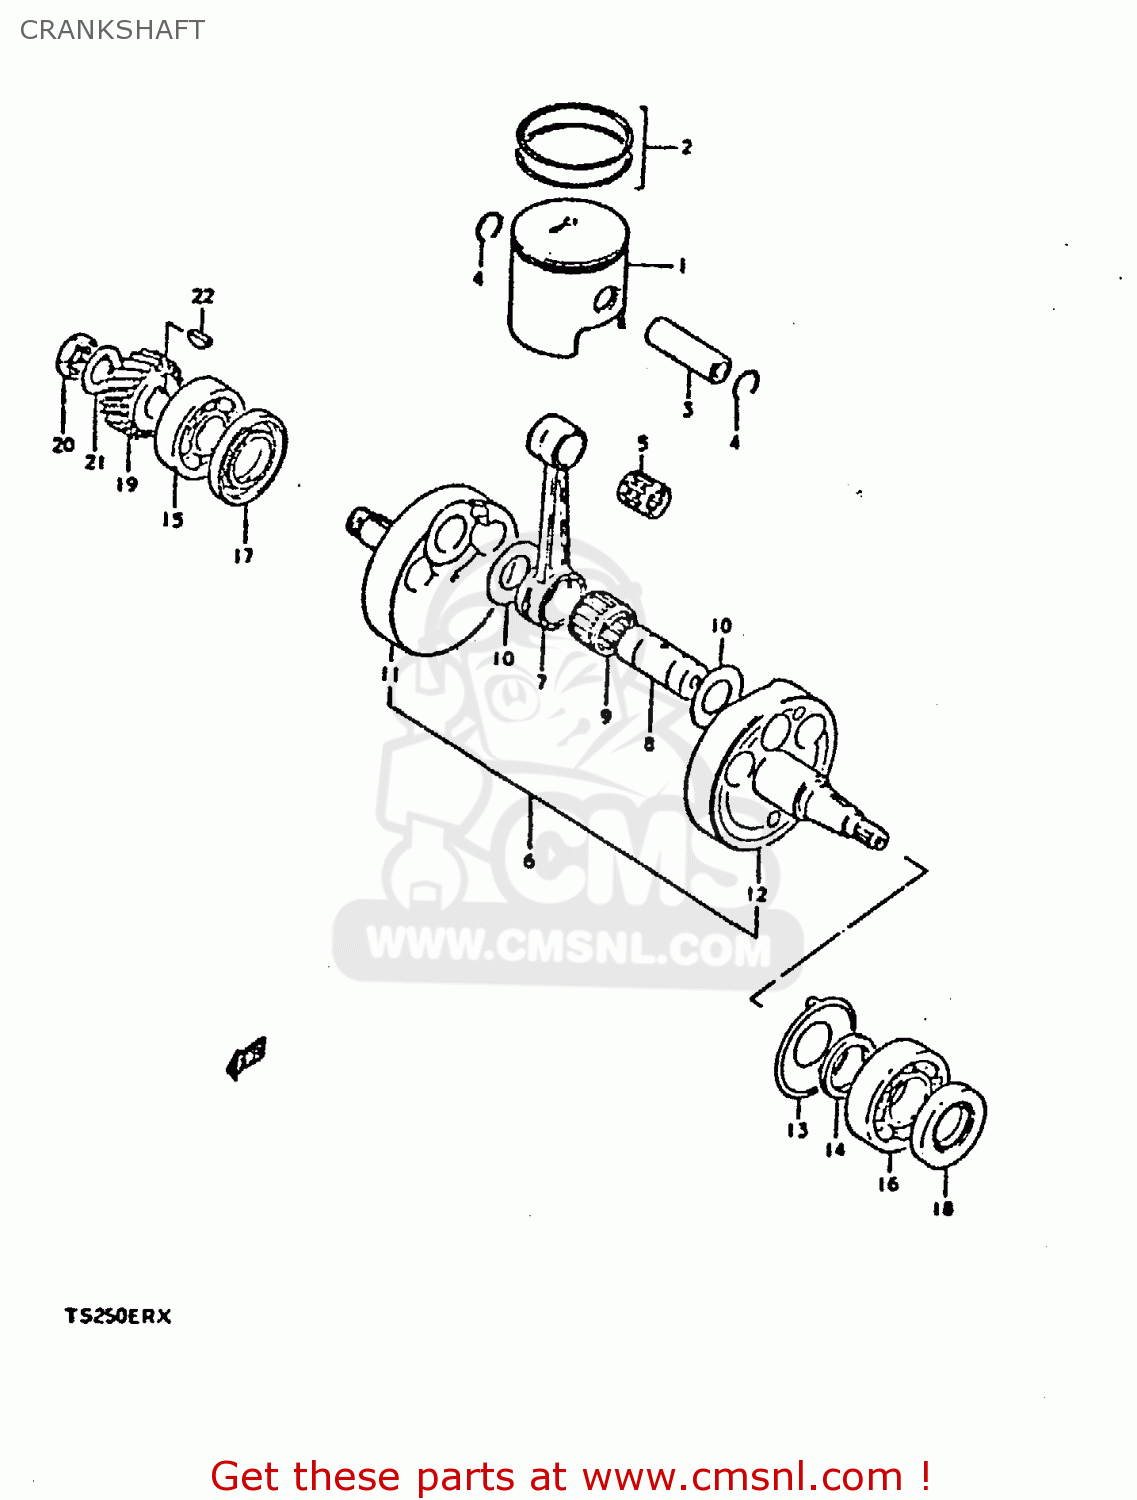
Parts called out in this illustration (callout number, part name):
1	PISTON
2	RING SET,PISTON
3	PIN,PISTON (18MM)
4	CIRCLIP,PISTON PIN
5	BEARING
6	CRANKSHAFT ASSEMBLY
7	ROD,CONNECTING
8	PIN,CRANK
9	BEARING(25X31X20)
10	WASHER(25X40X1)
11	CRANKSHAFT,RIGHT
12	CRANKSHAFT,LEFT
13	PLATE,CRANKSHAFT OIL GUIDE
14	SPACER (30X45X4.8)
15	BEARING
16	BEARING(30X72X19)
17	SEAL,OIL(35X62X9)
18	OIL SEAL
19	GEAR,PRIMARY DRIVE
20	NUT
21	WASHER
22	KEY
